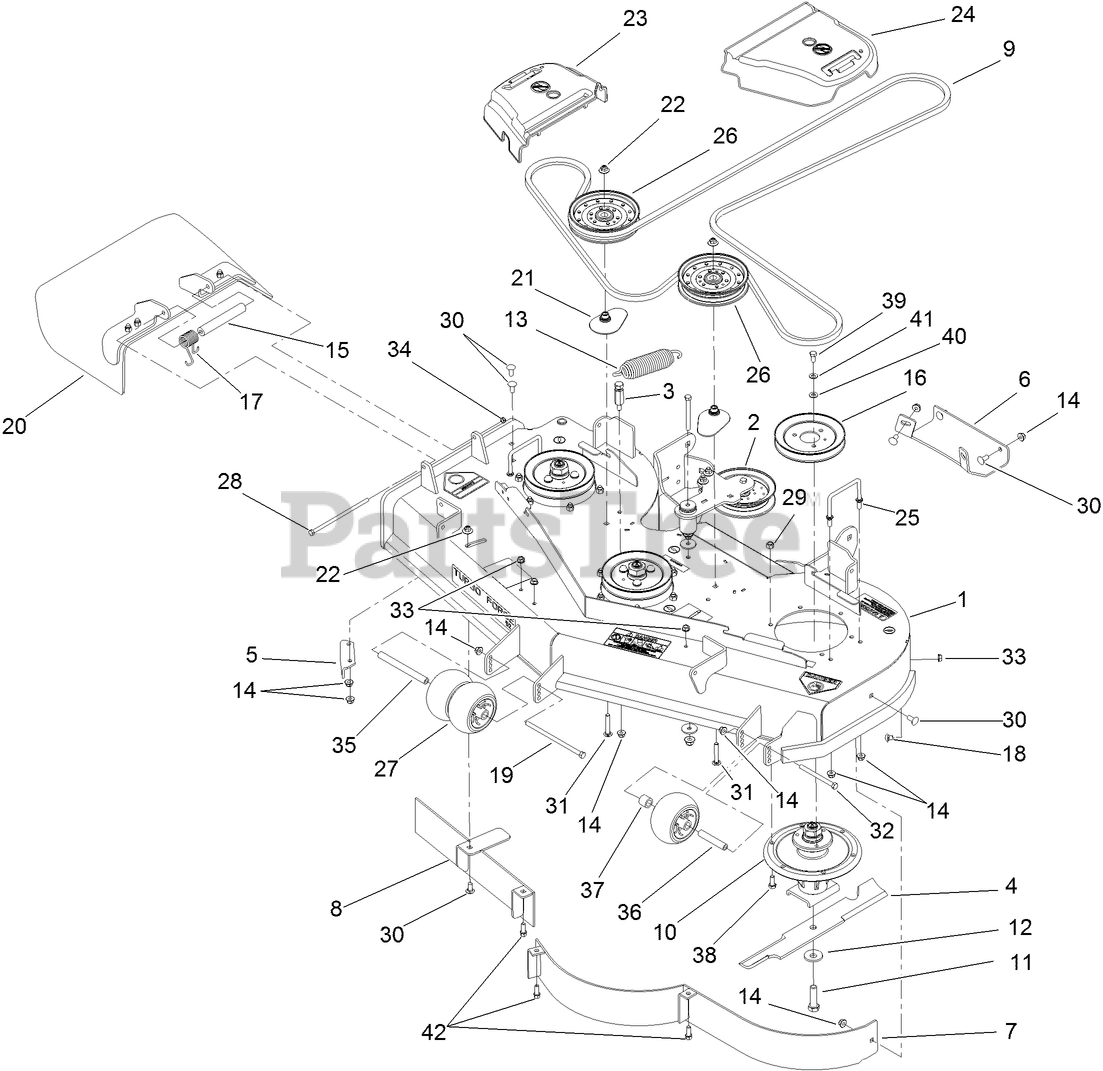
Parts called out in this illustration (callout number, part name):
1	DECK DECAL ASM
2	IDLER ARM ASM
3	ANCHOR-SPRING, TALL
4	BLADE-18IN, HI FLOW
5	BAFFLE-DISCHARGE
6	PLATE-SKID
7	BAFFLE ASM
8	BAFFLE ASM
9	BELT-V
10	SPINDLE ASM
11	SCREW-BLADE
12	Washer-Blade Bolt, Heavy
13	EXTENSION-SPRING
14	NUT-HF, NI
15	SPACER
16	PULLEY
17	SPRING-TORSION
18	SCREW-CARR
19	SCREW-HH
20	RUBBER DEFLECTOR ASM
21	SPACER-PULLEY
22	NUT-FLANGE, NI
23	COVER-BELT, RH
24	COVER-BELT, LH
25	WIREFORM-COVER
26	PULLEY-IDLER, FLAT
27	ROLLER-SCALP, ANTI
28	SCREW-HH
29	NUT-LOCK, NI
30	SCREW-CARR
31	BOLT-CARR, SHORT NECK
32	SCREW-HH
33	NUT-HHF, WHIZ
34	NUT-LOCK, NI
35	SPACER-WHEEL
36	TUBE-SPANNER
37	TUBE-SPACER
38	SCREW-HH
39	SCREW-HH
40	WASHER-FLAT
41	WASHER-BELLEVILLE
42	SCREW-HWH
